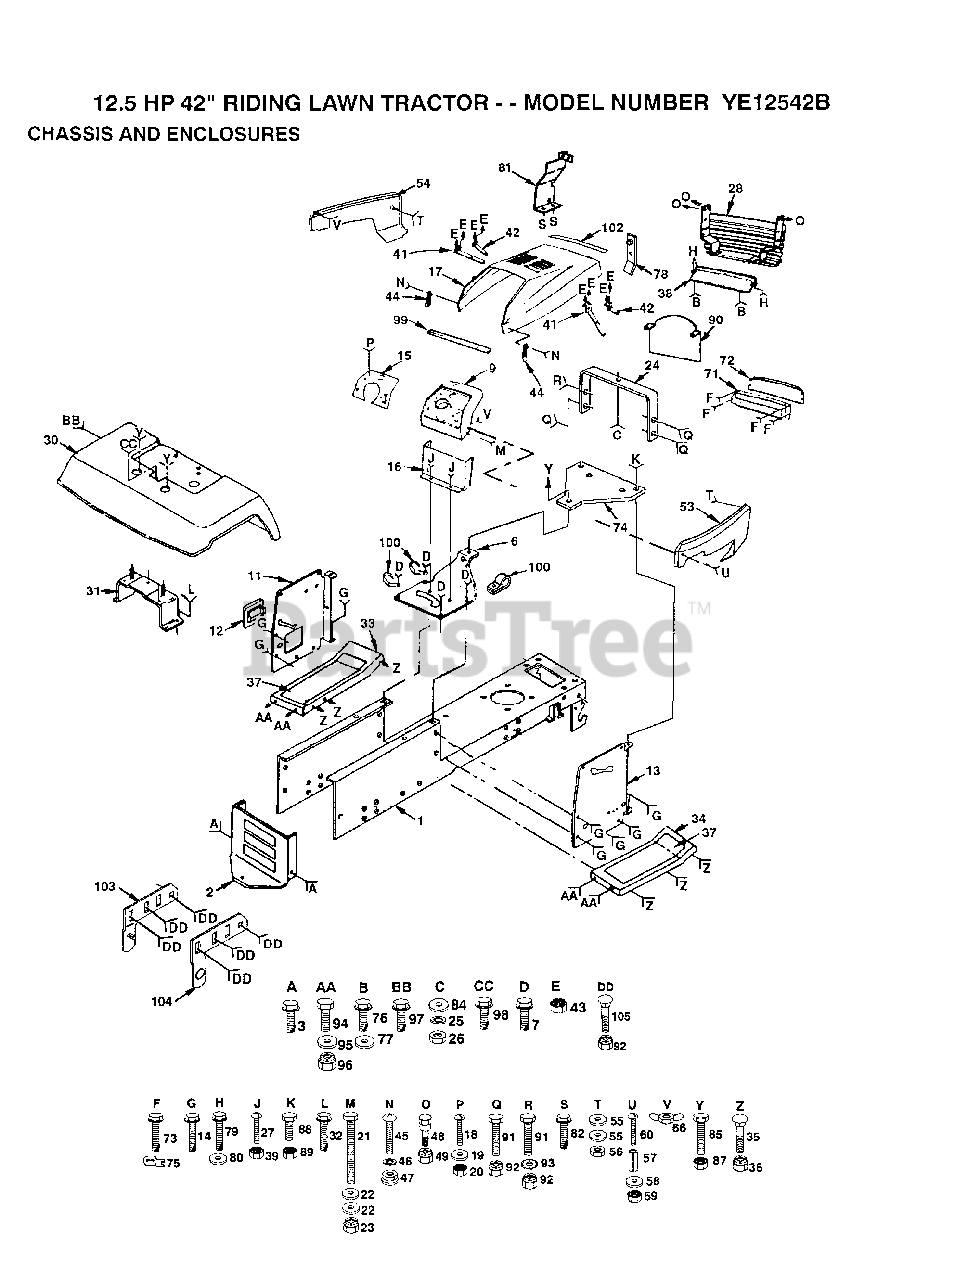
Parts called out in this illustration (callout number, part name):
3	SCREW
7	SCREW LT
12	COVER ACCESS
14	SCREW
16	DASH ASSY LT
18	SCREW
19	WASHER
24	SUPPORT ASS'Y
25	LOCKWASHER
27	SCREW
30	FENDER
32	SCREW
35	BOLT
37	FOOTREST PAD
43	NUT
44	HOOD LATCH T
45	SCREW
46	LOCKWASHER
47	WELDNUT
53	"PANEL,SIDE RH"
54	"PANEL,SIDE LH"
55	WASHER PM
57	SPACER LT
58	WASHER
60	SCREW
72	LENS LT
75	"""J"" FASTENER LT"
76	SCREW
77	WASHER
79	SCREW HEX CRT
80	WASHER
82	SCREW
84	WASHER PM
85	BOLT
89	NUT
90	BAFFLE HOOD VERT
93	LOCKWASHER
95	WASHER
97	SCREW LT
98	SCREW
99	FOAM-STRIP LT
100	CLIP T
103	PIVOT BRKT LH
104	PIVOT BRKT RH
105	BOLT
